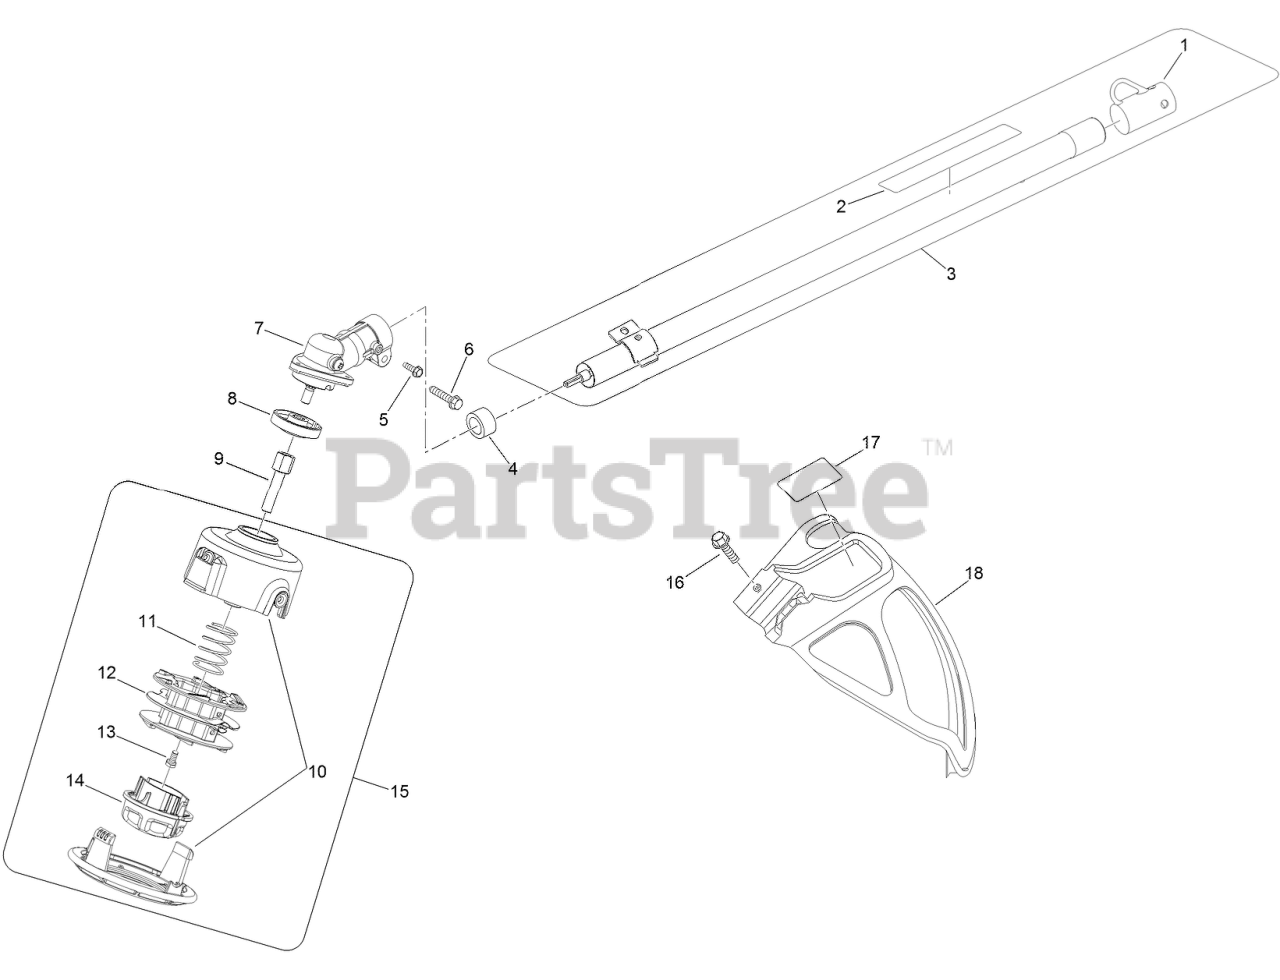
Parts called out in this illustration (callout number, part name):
1	CAP-HANGER
2	DECAL-WARNING
3	SHAFT ASM
5	SCREW-HWH
7	HEAD-GEAR
8	WASHER-FLANGE
9	ADAPTOR-HEAD SHAFT, TRIMMER
10	HOUSING-STRINGHEAD
11	SPRING-COMPRESSION
12	SPOOL
14	KNOB-BUMP
15	SPOOL HEAD ASM
16	SCREW-HWH
17	DECAL-GRASS DEFLECTOR
18	GRASS DEFLECTOR ASM
